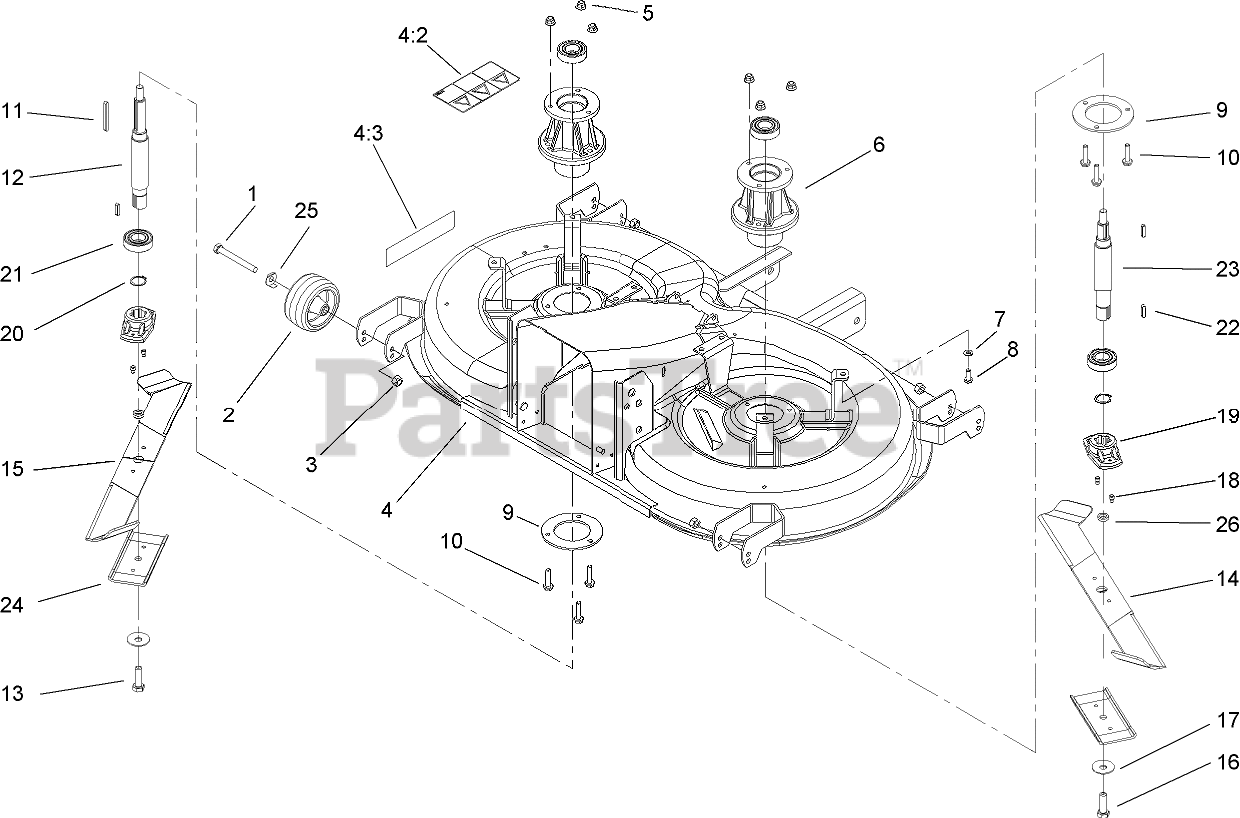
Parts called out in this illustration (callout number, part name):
1	SCREW-HH
2	WHEEL-GAUGE
3	NUT-LOCK, NI
4	DECK ASM
4:2	DECAL-DANGER
4:3	Decal-Recycler
5	NUT-LOCK, HHF
6	HOUSING-SPINDLE
7	WASHER-PLAIN
8	SCREW-HH
9	SUPPORT-RING
10	BOLT-HHF
12	Shaft-Blade, LEFT
13	BOLT-HH
14	BLADE-RH
15	BLADE-LH
16	BOLT-BLADE, HH
17	WASHER-BLADE
18	PIN-SHEAR, GROOVED
19	Adapter-Blade
20	RING-LOCKING
21	BEARING-BALL
22	KEY-SQUARE
23	Shaft-BLADE, Right
24	STIFFENER-BLADE
25	Washer
26	Spacer
